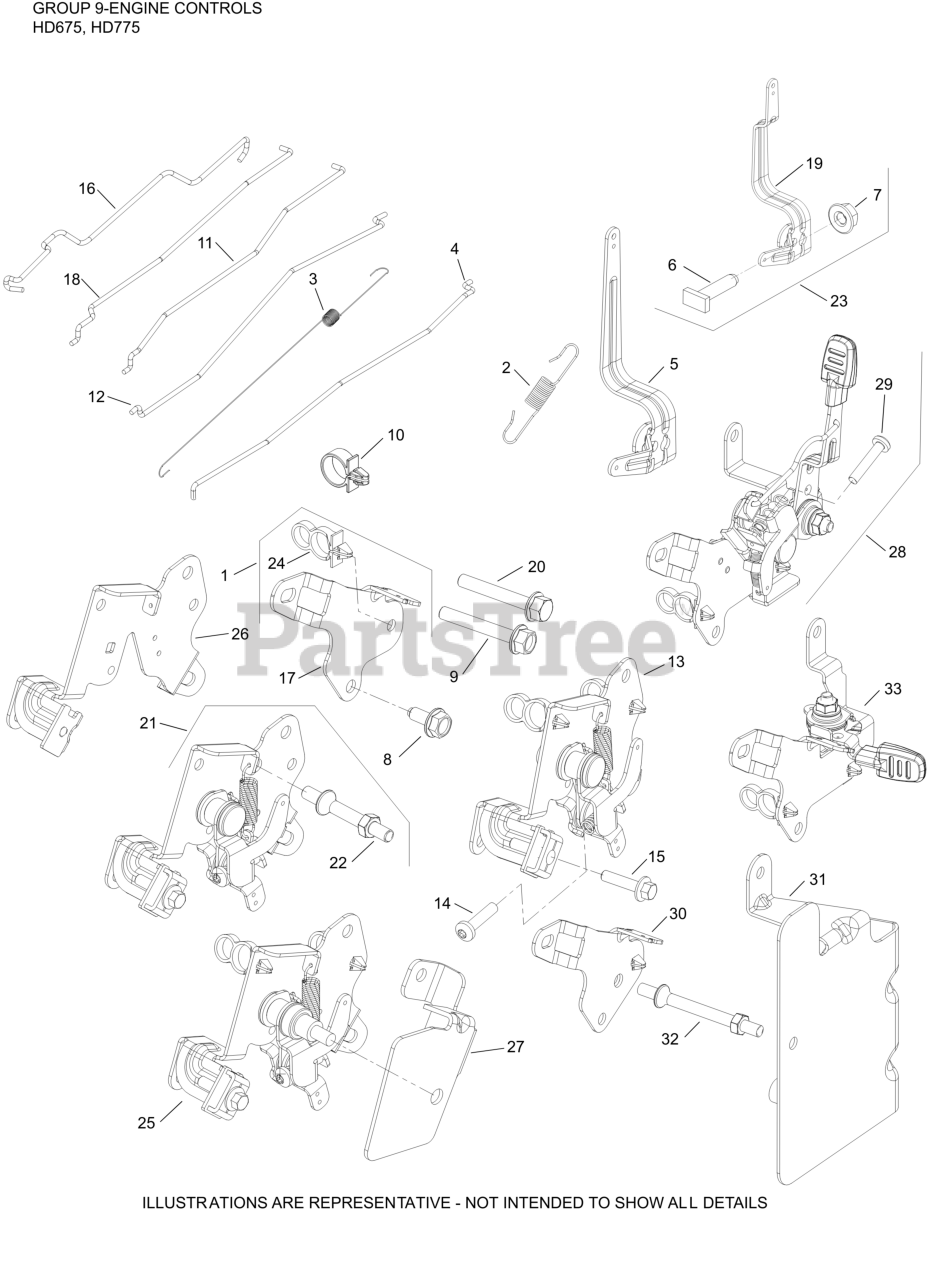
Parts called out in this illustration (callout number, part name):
2	SPRING, EXTENSION (GOVERNOR)
3	SPRING, LINKAGE
5	LEVER, GOVERNOR
6	SCREW, RECTANGLE HEAD (M6)
9	SCREW, HEX FLANGE (M6)
11	LINKAGE, GOVERNOR
12	LINKAGE, CHOKE
13	CONTROL ASSY, REMOTE VARIABLE SPEED
24	CLIP, FUEL LINE
